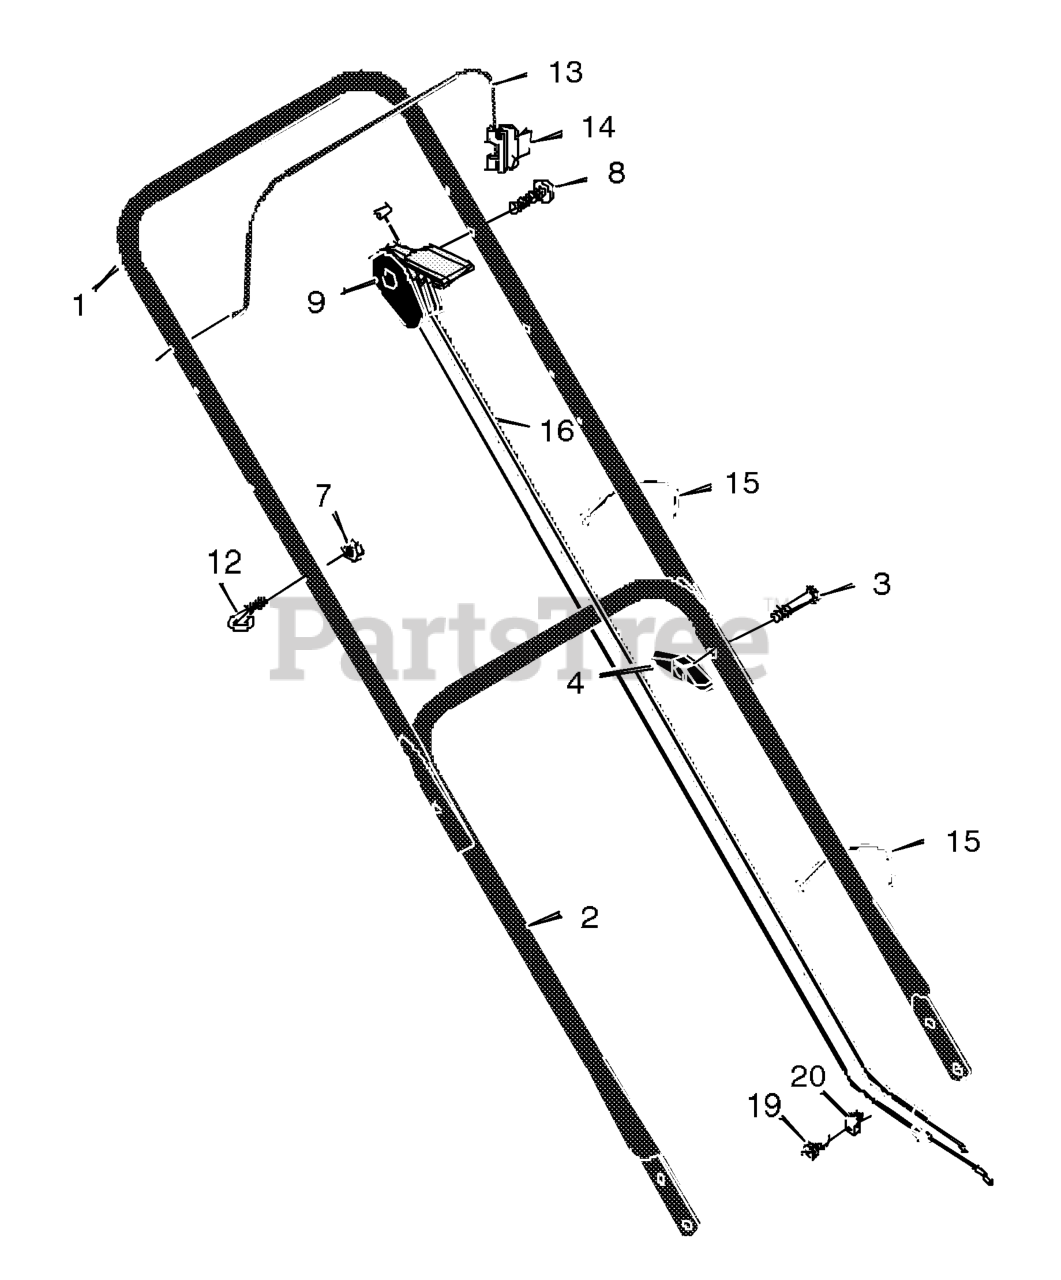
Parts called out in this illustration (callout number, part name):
1	Handle, Upper (Black)
2	Handle, Lower (Black)
4	Knob, Plastic
7	Locknut
9	Throttle Control
12	GUIDE, ROPE
13	Engine Stop Lever
14	Bracket, Stop Lever
15	Fastener, Cable
16	Engine Stop Cable
